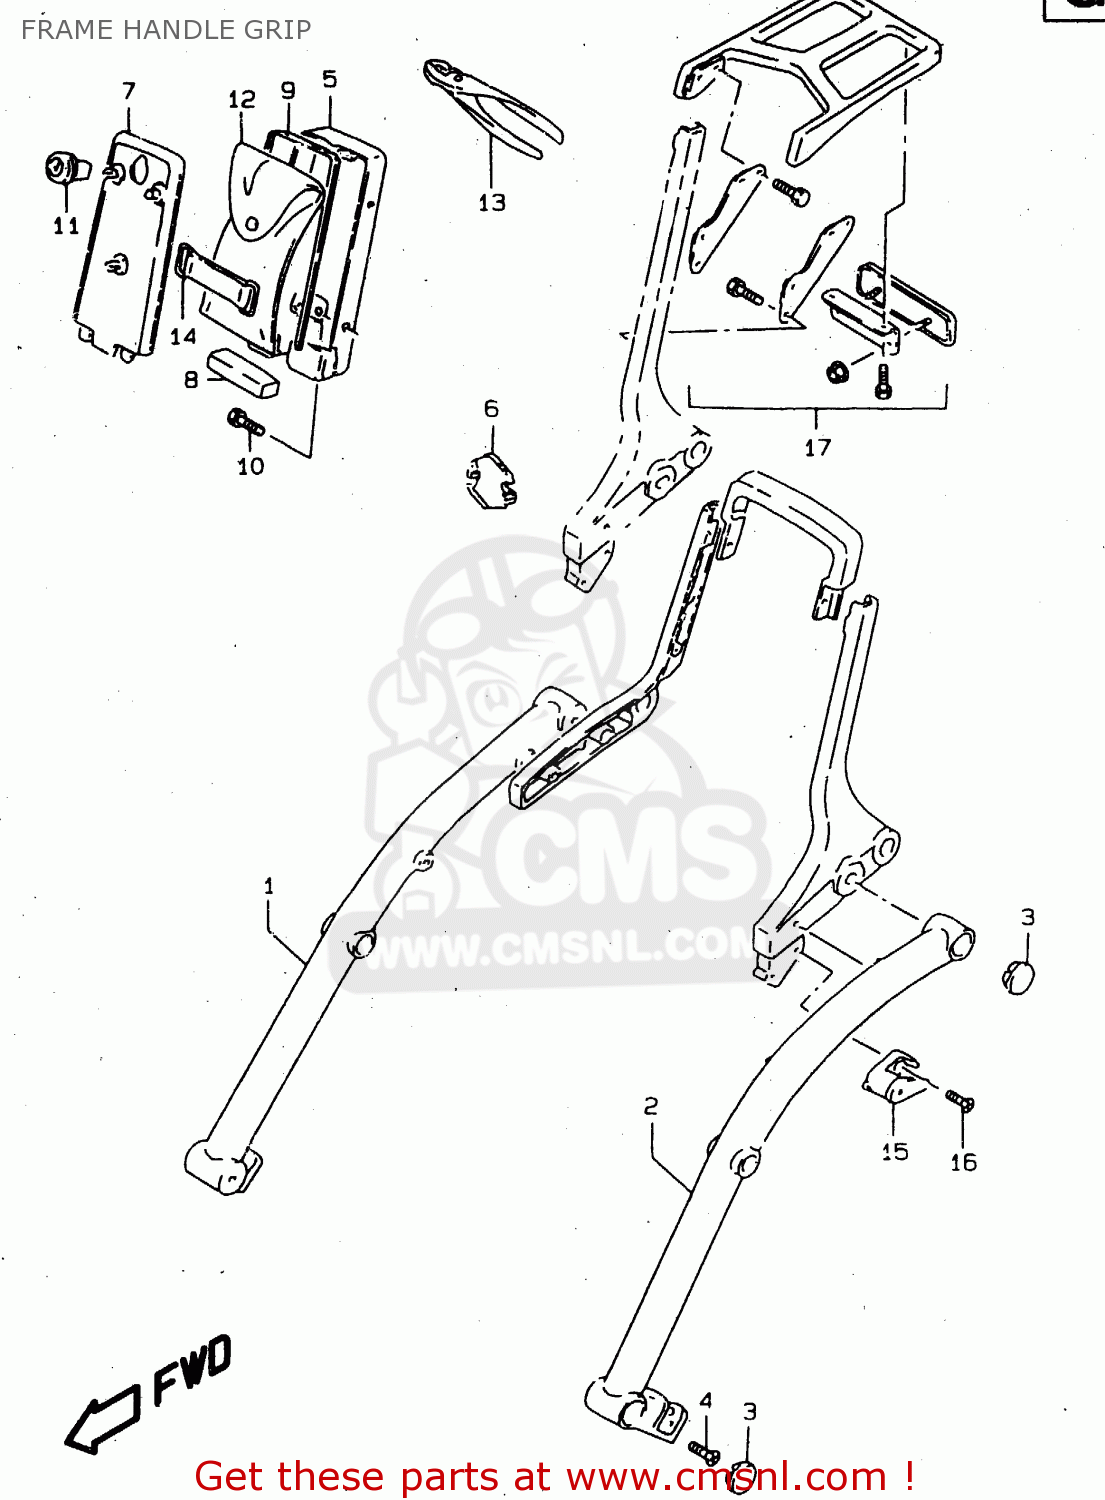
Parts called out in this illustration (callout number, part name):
1	GRIP,FRAME HANDLE RH
2	GRIP,FRAME HANDLE LH
3	CAP,FRAME HANDLE GRIP
4	BOLT
5	HOLDER,TOOL,REAR
6	EMBLEM,TOOL HOLDER RR
7	HOLDER,TOOL FR
8	CUSHION,TOOL BACK
9	MOLDING,TOOL HOLDER RR
10	BOLT
11	LOCK SET,TOOL HOLDER
12	TOOL ASSY
13	PLIER(150)
14	BAND
15	LOCK SET,HELMET
16	SCREW
17	CARRIER SET,SPORT
